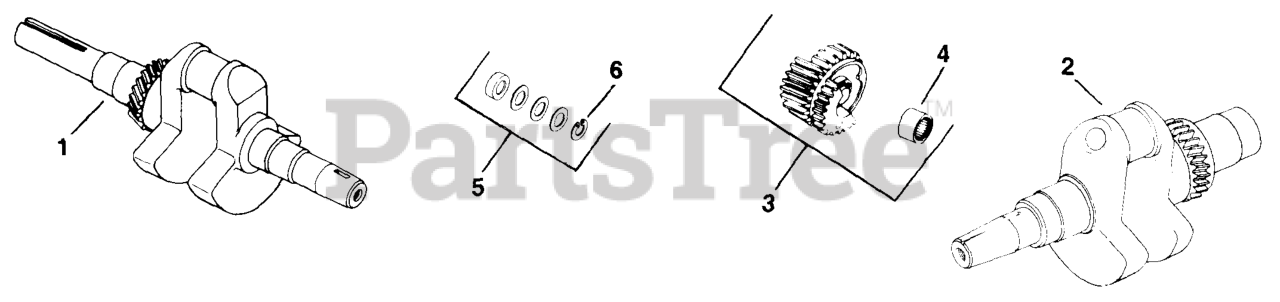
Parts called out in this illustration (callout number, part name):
1	CRANKSHAFT KIT
3	GEAR
4	BEARING
5	KIT, SPACER
